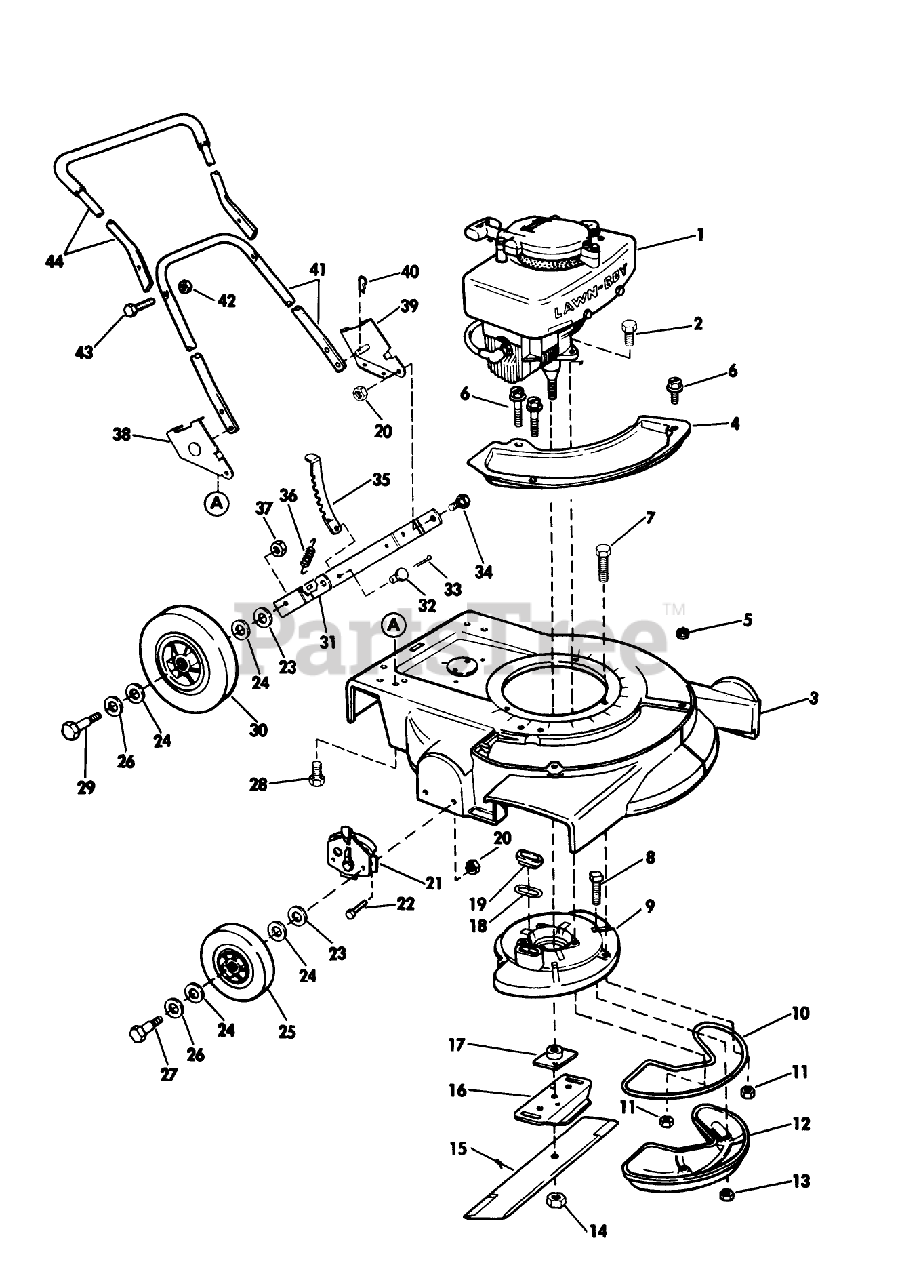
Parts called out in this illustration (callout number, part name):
6	SCREW SEMS TRM HEX HD
7	SCREW
11	NUT
13	LOCKNUT E
14	NUT-BLADE
17	PLATE AND COLLAR ASM
18	GASKET S
19	SLEEVE
20	NUT
23	WASHER WROUGHT
24	WASHER
25	WHEEL & TIRE KIT
26	SPACER
27	BOLT WHEEL
29	BOLT
34	BOLT-SHOULDER
36	SPRING N.A.S
37	LOCKNUT
40	HAIR PIN
43	SCREW
